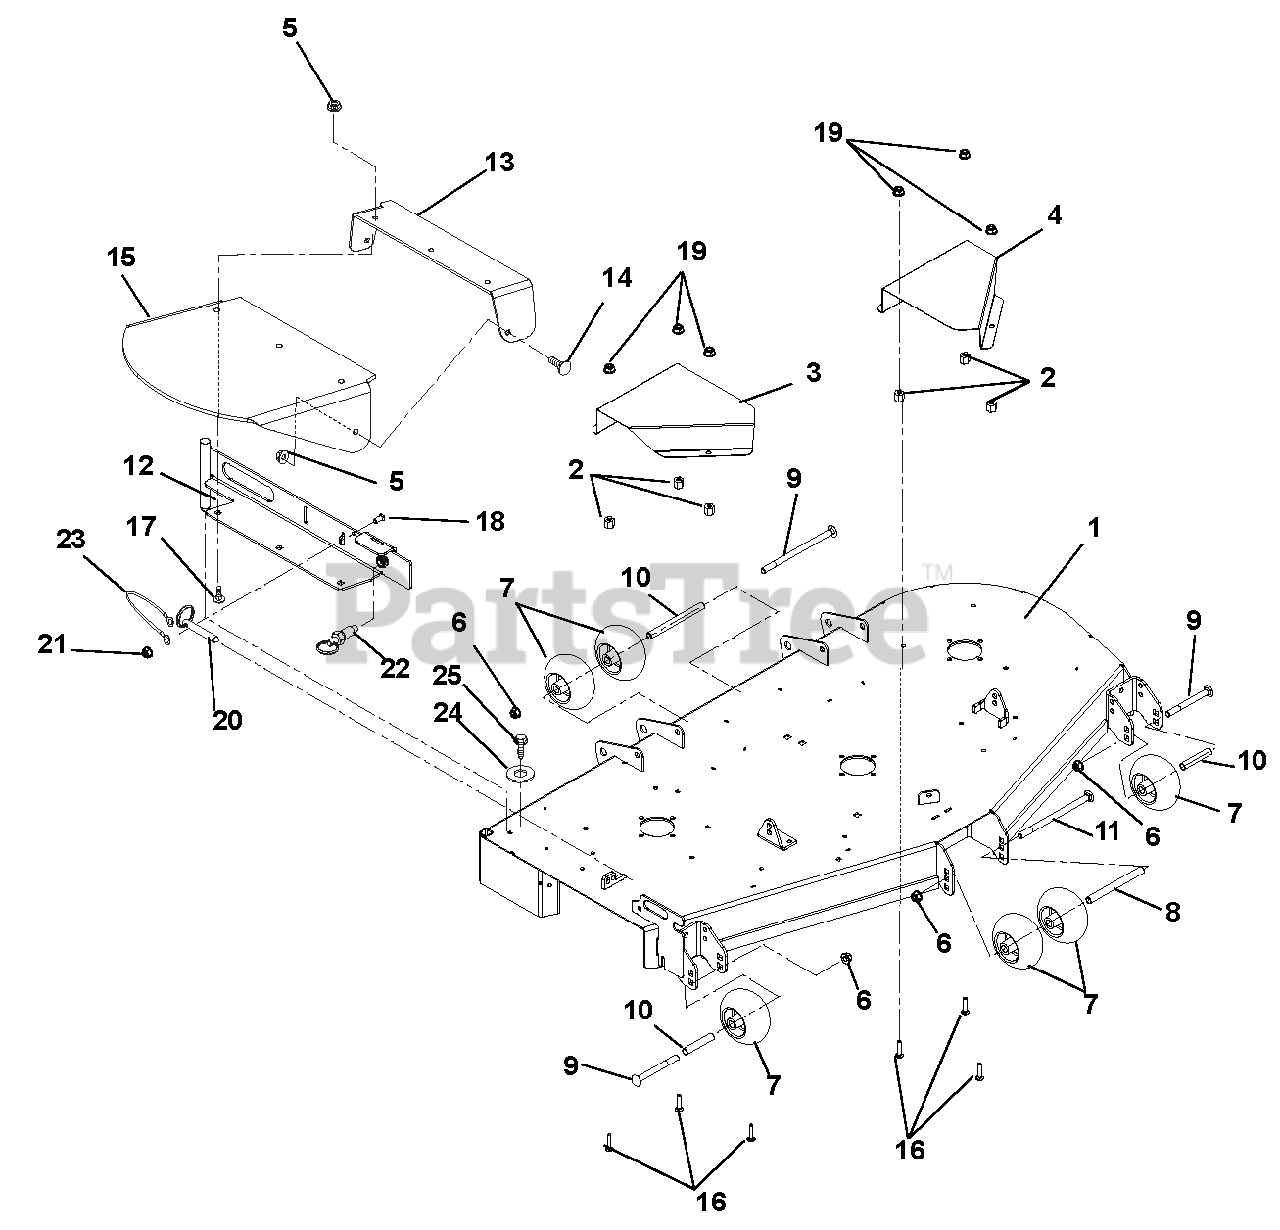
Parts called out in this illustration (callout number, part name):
1	WLDMT, 60" HD SIDE DISCH DECK
1	WLDMT, 52" DECK
1	WLDMT, 48" DECK
2	NUT-HEAVY HEX .38-16 YWZC
3	60" RH BELT GUARD
3	GUARD-44-52 RH SPINDLE SHEAVE
4	60" LH BELT GUARD
4	44-52" LH DECK BELT GUARD
5	@NUT-LK-NYL-FLG .38-16 YWZC
6	@NUT-LK-NYL-FLG .50-13 YWZC
7	ANTI-SCALP WHEEL - 5X3 CTR
8	SPACER, .510X.625X6.50
9	BLT-RDHDSQNK .50-13X5.00 GR5YZ
10	SPACER, .510X.625X3.35
11	@BLT-RDHDSQNK .50-13X8.50 G5YZ
12	WMT, 44"-48" DISCH CHUTE MTG
12	WMT, 52"-60" DISCH CHUTE MTG
13	SUPPORT, RUBBER DISCH CHUTE HD
14	@BLT-RDHDSQNK .38-16X1.00 G5YZ
15	CHUTE, RUBBER DISCHARGE
16	@BLT-HEX .38-16X1.25 GR5 YWZC
17	@BLT-RDHDSQNK .38-16X1.25 G5YZ
18	@BLT-HEX .25-20X.75 GR5 YWZC
19	@NUT-SPNLK-FLG .375-16 YWZC
20	PIN, SPRING BALL .375OD X 1.50
21	@NUT-LK-TOP-FLG .25-20 YWZC
22	PULL PIN,.50-13THDX.310 PLNGR
23	CABLE, 6.0 LANYARD, NYLON
24	BUMPER,RECESSED1.50X.63 W/.31
25	@SCR-TAP .31-18X.75 HWH TR YWZ
